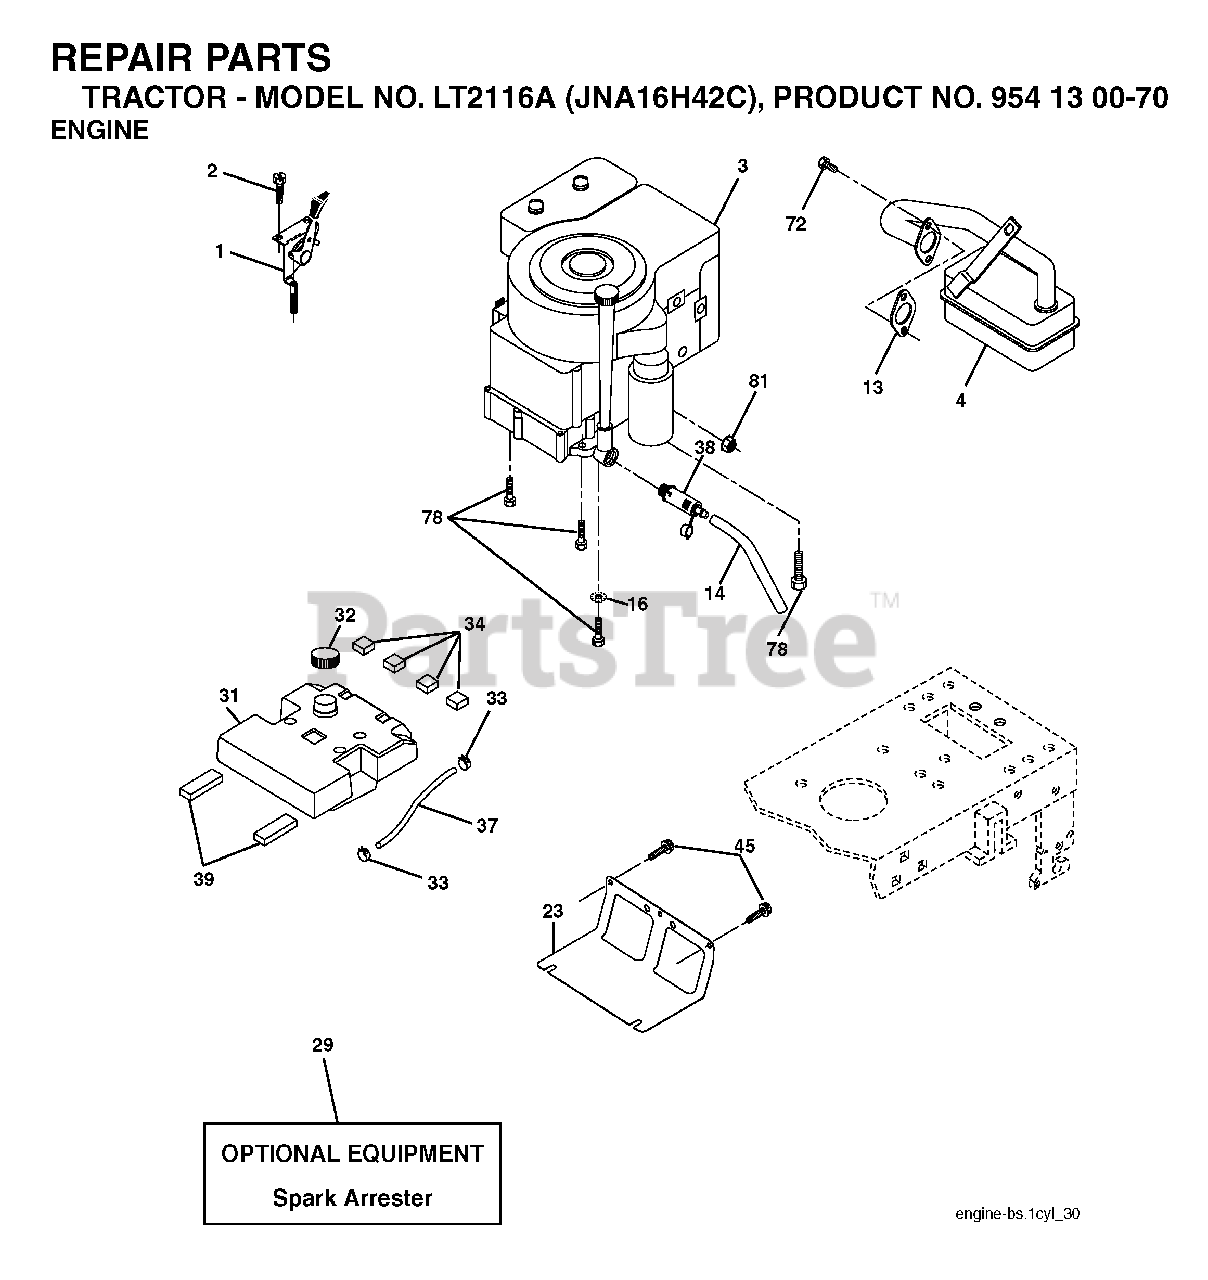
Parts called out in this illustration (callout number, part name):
1	CONTROL TH/CH FLAG
2	SCREW
13	REPL BY 532 27 22-93
14	TUBE, DRAIN OIL ASM.
16	LOCKWASHER
23	SHEILD.BROWNING.DBR.GUARD
29	ARRESTER SPARK (OPTIONAL)
31	TANK.FUEL(3.5.GAL)
32	FUEL CAP
33	HOSE CLAMP
34	PAD-SPACER LT
38	PLUG DRAIN OIL EASY
39	PAD IDLER TI
45	SCREW, 3/8-16X3/4
72	SCREW.SOCKET.HEAD.5/16-18
78	SCREW.3/8-16
81	NUT
